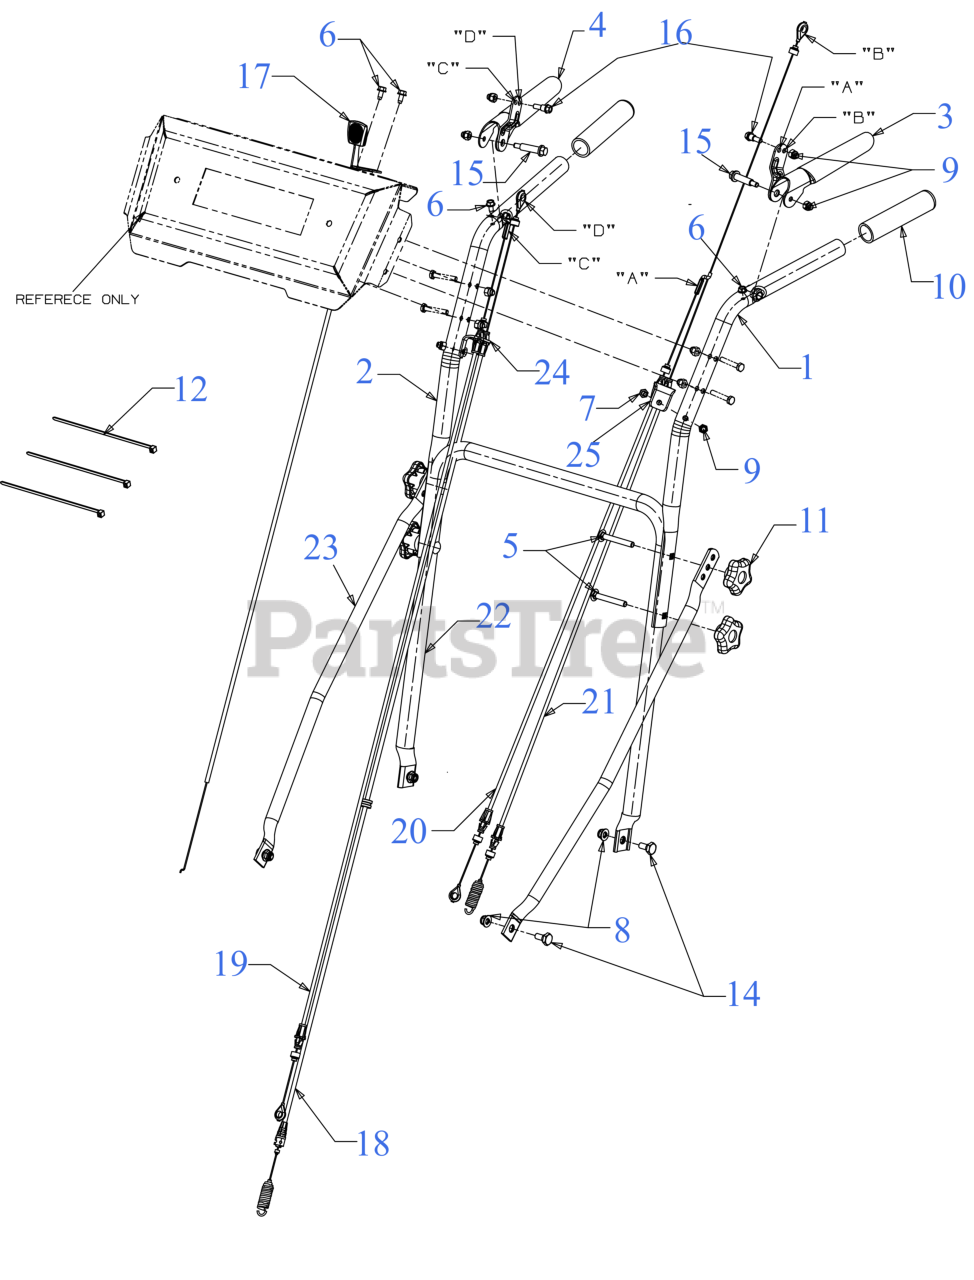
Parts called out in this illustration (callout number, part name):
1	HANDLE ASSEMBLY (UPPER) (LH)
2	HANDLE ASSEMBLY (UPPER) (RH)
3	LEVER ASSEMBLY (LH)
4	LEVER ASSEMBLY (RH)
5	BOLT 5/16-18 x 2.50 GR1
6	SCREW 1/4-20 X.500
7	SCREW 1/4-20 x 1.50 GR.5
8	FLANGE LOCK NUT 5/16-18
9	HEX ACORN NUT
11	STAR KNOB 5/16-18
12	7" CABLE TIE
14	SHOULDER SCREW .437
15	SHOULDER BOLT .375X1.285:1/4-20
16	SHOULDER SCREW .342X.335X1/4-20
17	THROTTLE/CHOKE CABLE 38" x 1.1
18	BLADE CONTROL CABLE
19	TRANSMISSION BRAKE CABLE (RH)
20	TRANSMISSION BRAKE CABLE (LH)
21	WHEEL CLUTCH CABLE
22	HANDLE (LOWER)
23	HANDLE BRACE TUBE
24	CABLE BRACKET MOUNTING (RH)
25	CABLE BRACKET MOUNTING (LH)
